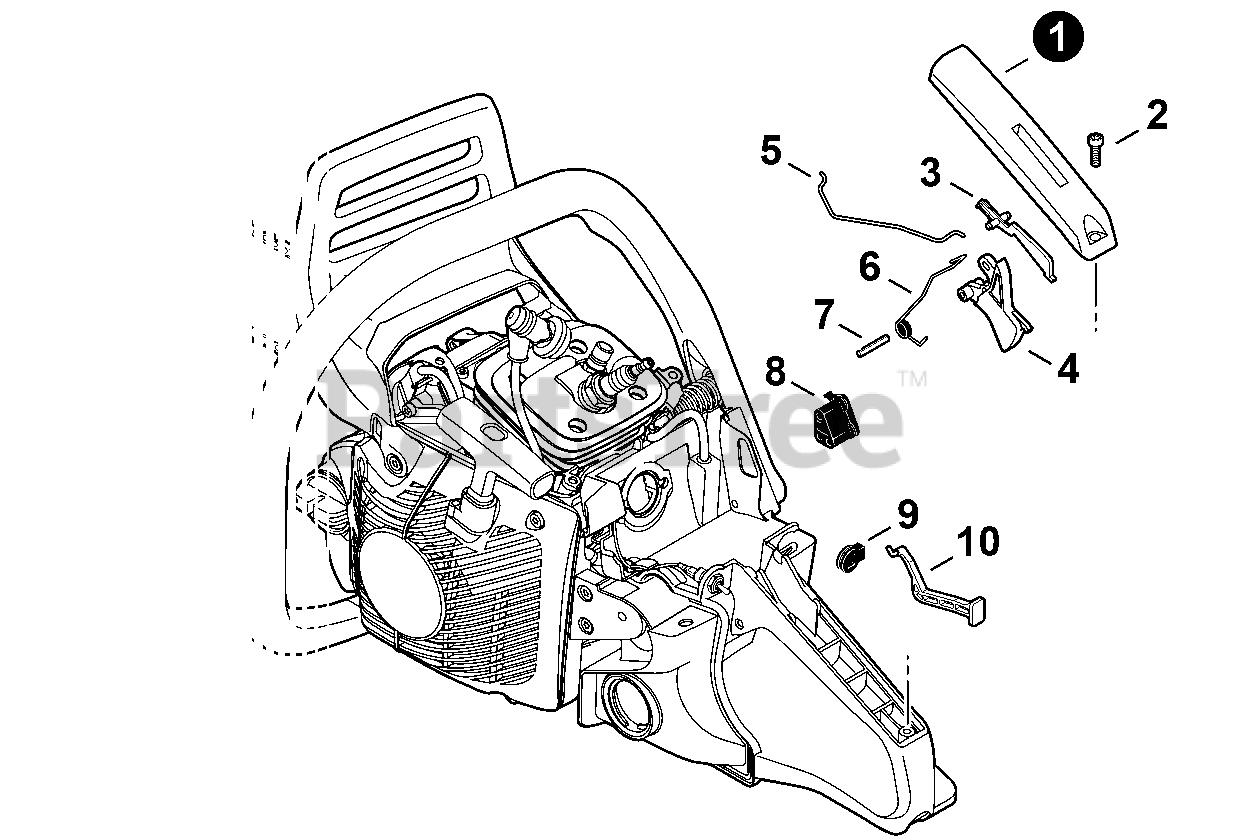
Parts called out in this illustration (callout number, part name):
1	COVER, HANDLE
2	BOLT, TORX 4×12
3	LEVER, THROTTLE LOCKOUT
4	TRIGGER, THROTTLE
5	ROD, THROTTLE
6	SPRING, TORSION
7	PIN, SPRING 4×25 SUS
8	GROMMET, NEEDLE
9	GROMMET, CHOKE
10	ROD, CHOKE
